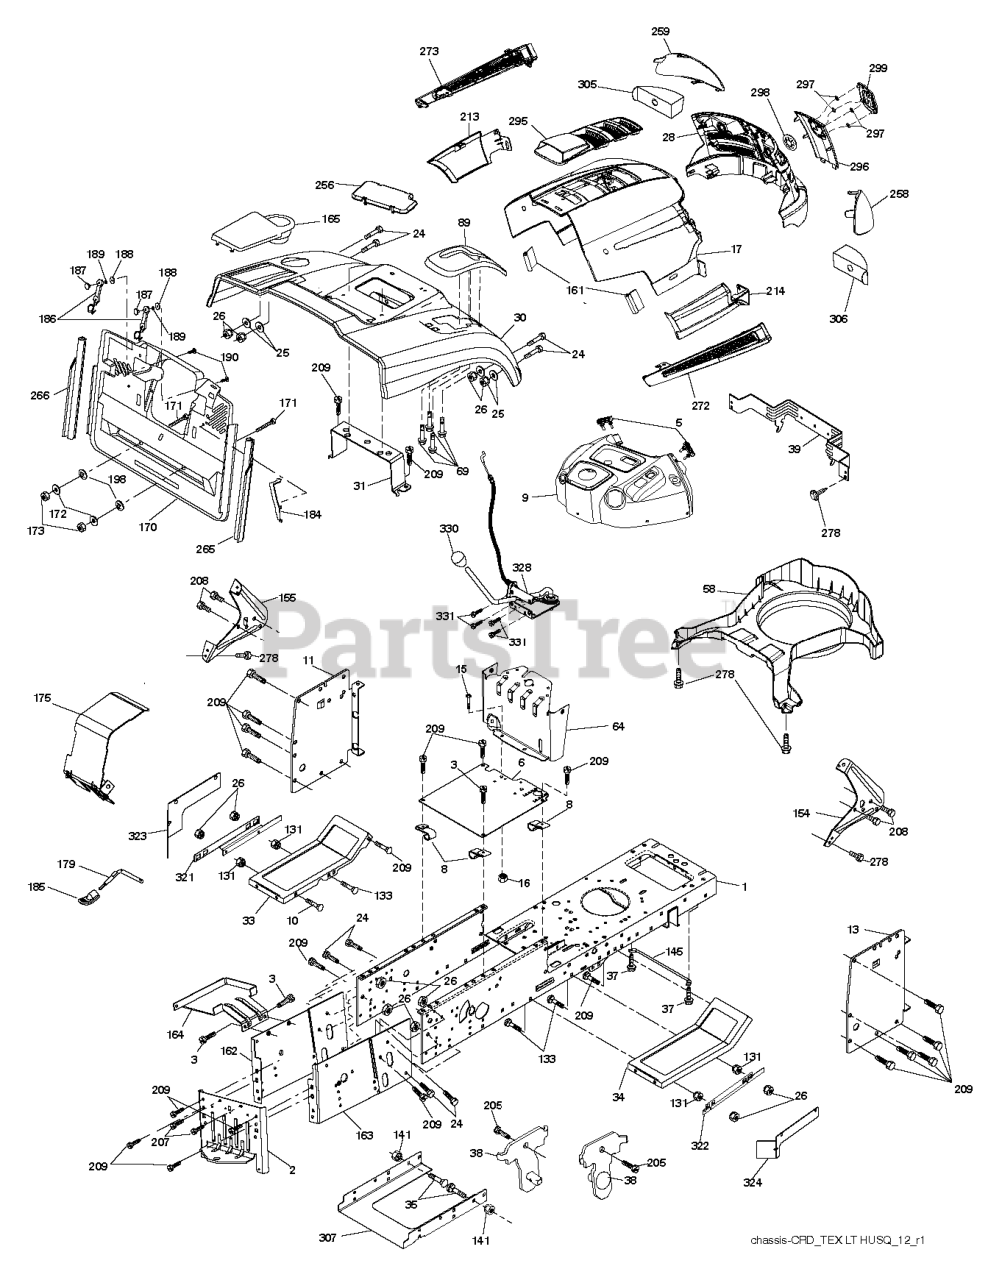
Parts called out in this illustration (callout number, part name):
2	DRAWBAR
3	SCREW 3/8-16X3/4
5	BUMPER DASH
6	PLATE
8	CLIP,INSULATOR
10	BOLT.3/8-14X1.25
11	PANEL.DASH.LH.LTX
15	Screw, Machine, Truss Head 5/16-18 UNC x 3/4
16	NUT
17	HOOD.HUSQVARNA.LT.ORANGE
25	WASHER
26	NUT
28	GRILLE.SVC.HUSQVARNA.LT.GREY
30	FENDER.PNT.CRD.MS-668
31	BRACKET SUPPORT FENDER
33	FOOTREST PNT LH
34	FOOTREST PNT RH
37	Screw 5/16-18 x 1/2 Hex, Self Tapping 5/16-18 x 1/2
38	BRACKET ASM PIVOT MOWER REAR
39	BRACKET PIVOT
69	SCREW.HI-LO.CONSOLE
131	NUT.HEX.3/8-16UNC
133	BOLT D
141	NUT LOCK FLG 3/8-16 UNC
145	ROD.PIVOT.HOOD
161	BUMPER.HOOD.TEX.HUSQVARNA
162	BRACKET
163	BRACKET EXTEN CHASSIS RH CRD
165	COVER.BATT.CUPHOLDER.CRD
172	WASHER
175	DOOR TRAP
179	ROD PIVOT FBI
184	BRACKET.ACTUATOR.BAGGER.SRD
185	KNOB.BRAKE.PARKING.ROD
186	LATCH ASSY
187	WELDNUT
189	LOCKWASHER #10
190	SCREW
207	SCREW, 5/16-18 X 1/2
208	SCREW 3/8-16X1/2
209	SCREW, 3/8-16X3/4
213	SKIRT.SIDE.HUSQVARNA.LT.LEFT
214	SKIRT.SIDE.HUSQVARNA.LT.RT
256	COVER FENDER CRD
258	LENS.HUSQVARNA LT.RH
259	LENS.HUSQVARNA LT.RH
265	SEALING
266	SEALING
272	VENT.SIDE.HUSQVARNA.LT.RT
273	VENT.SIDE.HUSQVARNA.LT.LFT
278	SCREW.#10 X 0.750.BOS
295	SUBASM.TOP.VENT.HUSQ.LT
296	TRIM.HUSQ LT.668
297	CLIP.RETAINER.TINNER.
299	RP LOGO
305	INSERT REFLECTIVE
306	INSERT.REFLECTIVE.RH.
321	SHIELD INNER LEFT
322	SHIELD INNER RIGHT
323	PLATE LEFT
324	PLATE RIGHT
330	RP KNOB.OVAL.TAPERED.3/8-16BLK
331	SCREW.#10-24X5/8.RN.QU
